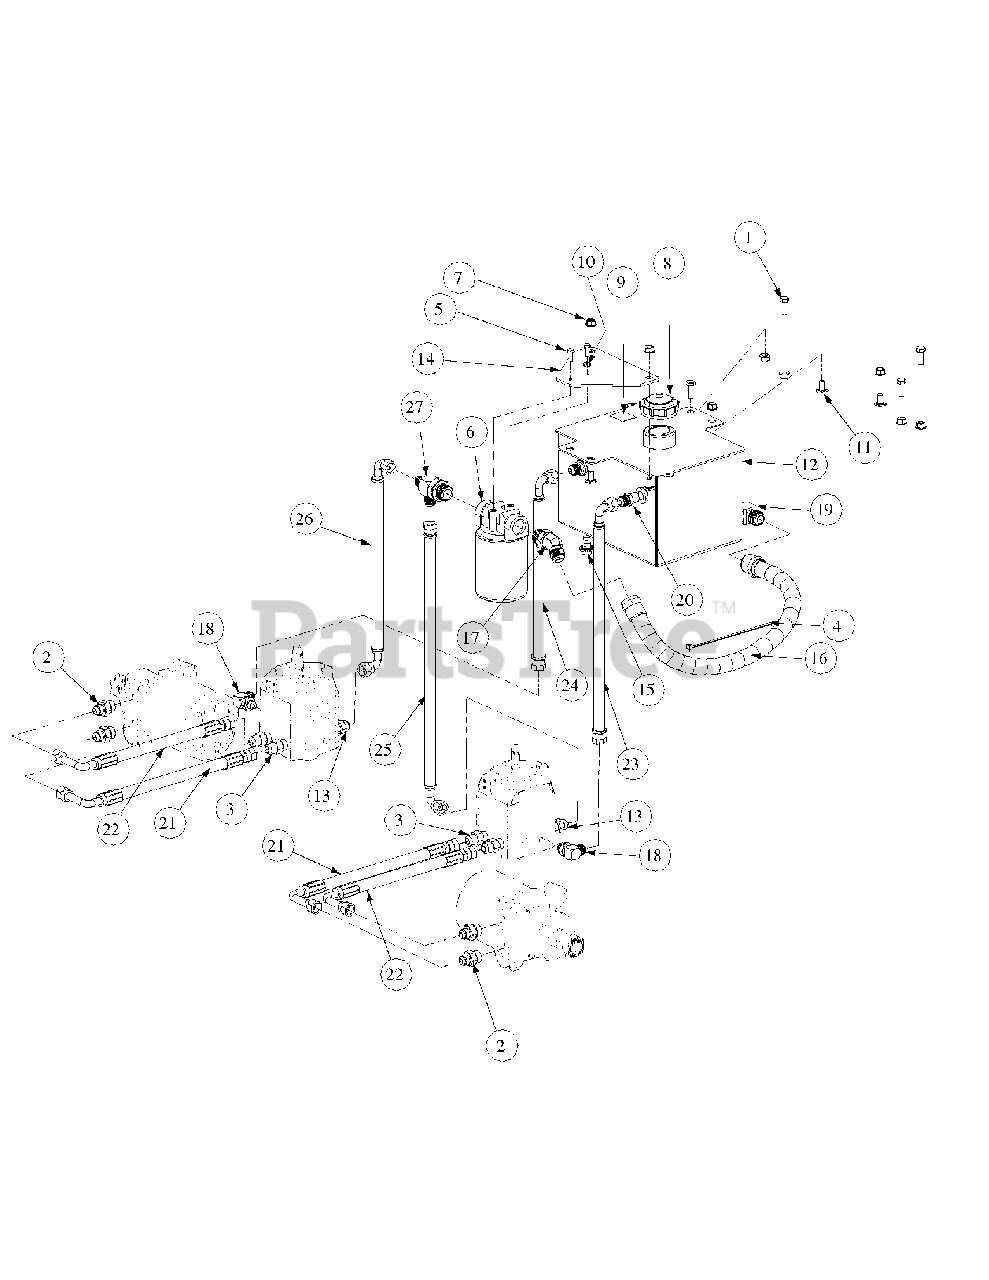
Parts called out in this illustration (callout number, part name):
1	Hex Cap Screw, 3/8-16, 1
2	Fitting 1/2 x 3/4 - O Ring
3	Fitting 1/2 x 3/4 - O Ring to Flare
4	Cable Tie, 3/16 x .05 x 7.4
5	Hex Cap Screw, 1/4-20, .75
6	Filter Head 3/4
7	Hex Nut Flange Lock, 3/8-16
8	Cap, Hydro Oil Tank
9	Decal Oil Only 20W50
10	Lock Washer, 1/4
11	Carriage Bolt, 3/8-16 x .75 LG.
12	Hydraulic Tank Assembly
13	Fitting Connector, 1/2 x 3/8
14	Oil Filter Mounting Plate
15	Oil Pan Drain w/ Seal and Plug
16	Tank to Filter Hose Assembly
17	Connector, 3/4 x3/4
18	Elbow Fitting, 3/8 O-ring, 1/2 Flare
19	Fitting Elbow, 1/2 x 1/2
20	Fitting, 3/8 NPT, 1/2 Flare
21	Long Pressure Hose Assembly
22	Short Pressure Hose Assembly
23	17.75" Return Hose Assembly, RH
24	14" Return Hose Assembly, LH
25	21.25" Supply Hose Assembly, RH
26	15.50" Supply Hose Assembly, LH
27	Tee Fitting, 3/4 x 1/2 x 1/2
